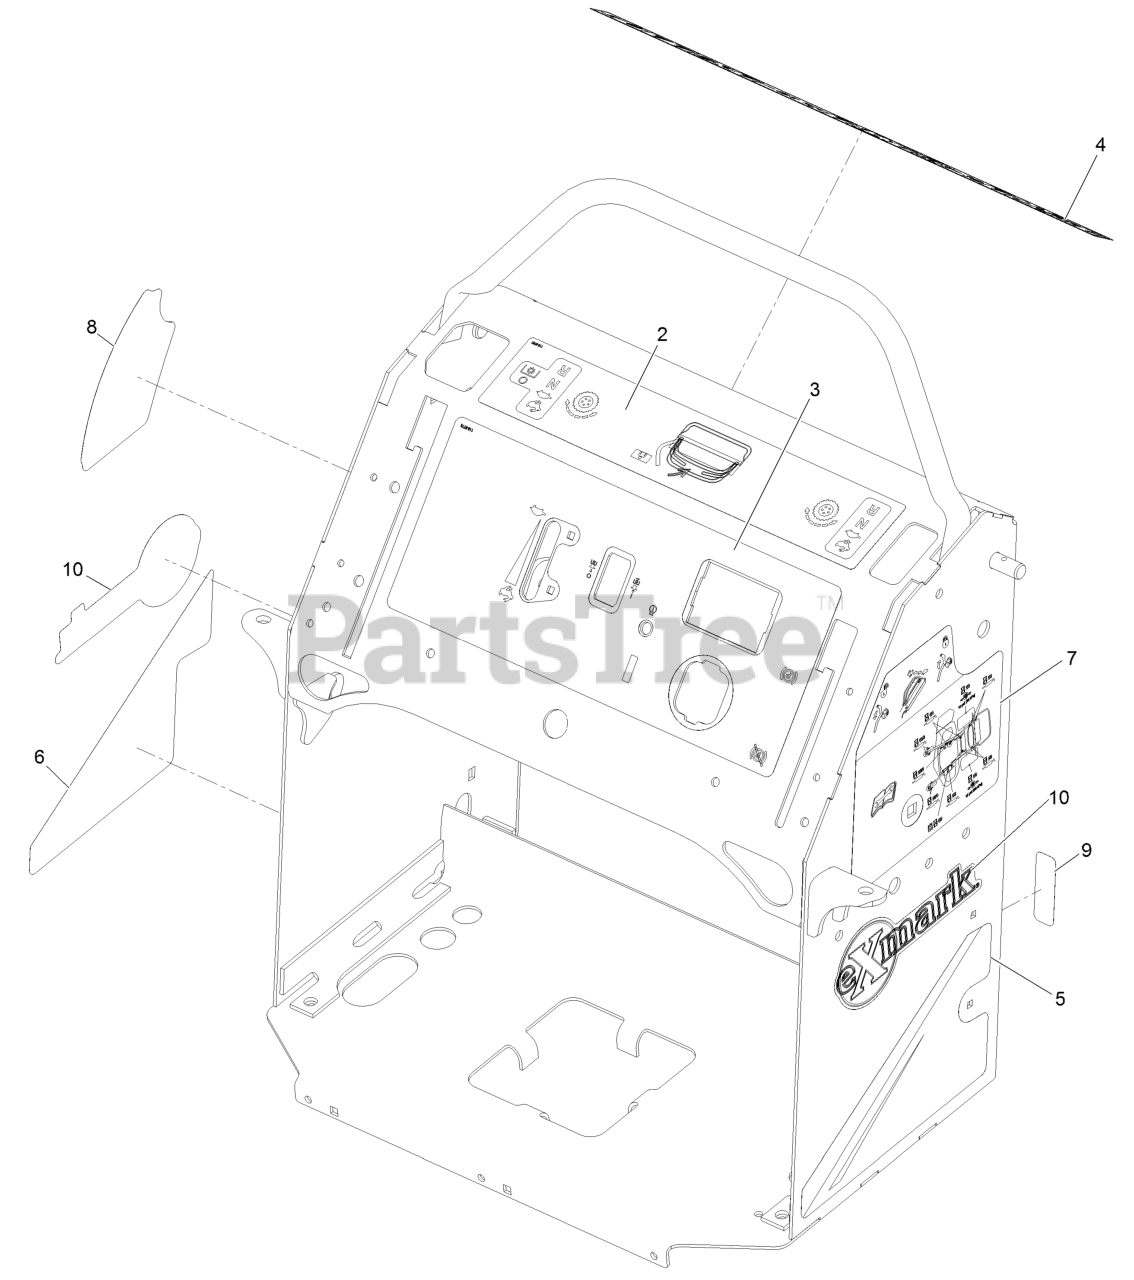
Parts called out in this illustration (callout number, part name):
2	DECAL-CONTROL PANEL EFI
3	DECAL-MOTION CONTROL
4	DECAL-WARNING
5	DECAL-LH PANEL
6	DECAL-RH PANEL
7	DECAL-SERVICE AID
8	DECAL-HEIGHT OF CUT
9	DECAL-FUSE
10	DECAL-EXMARK LOGO
